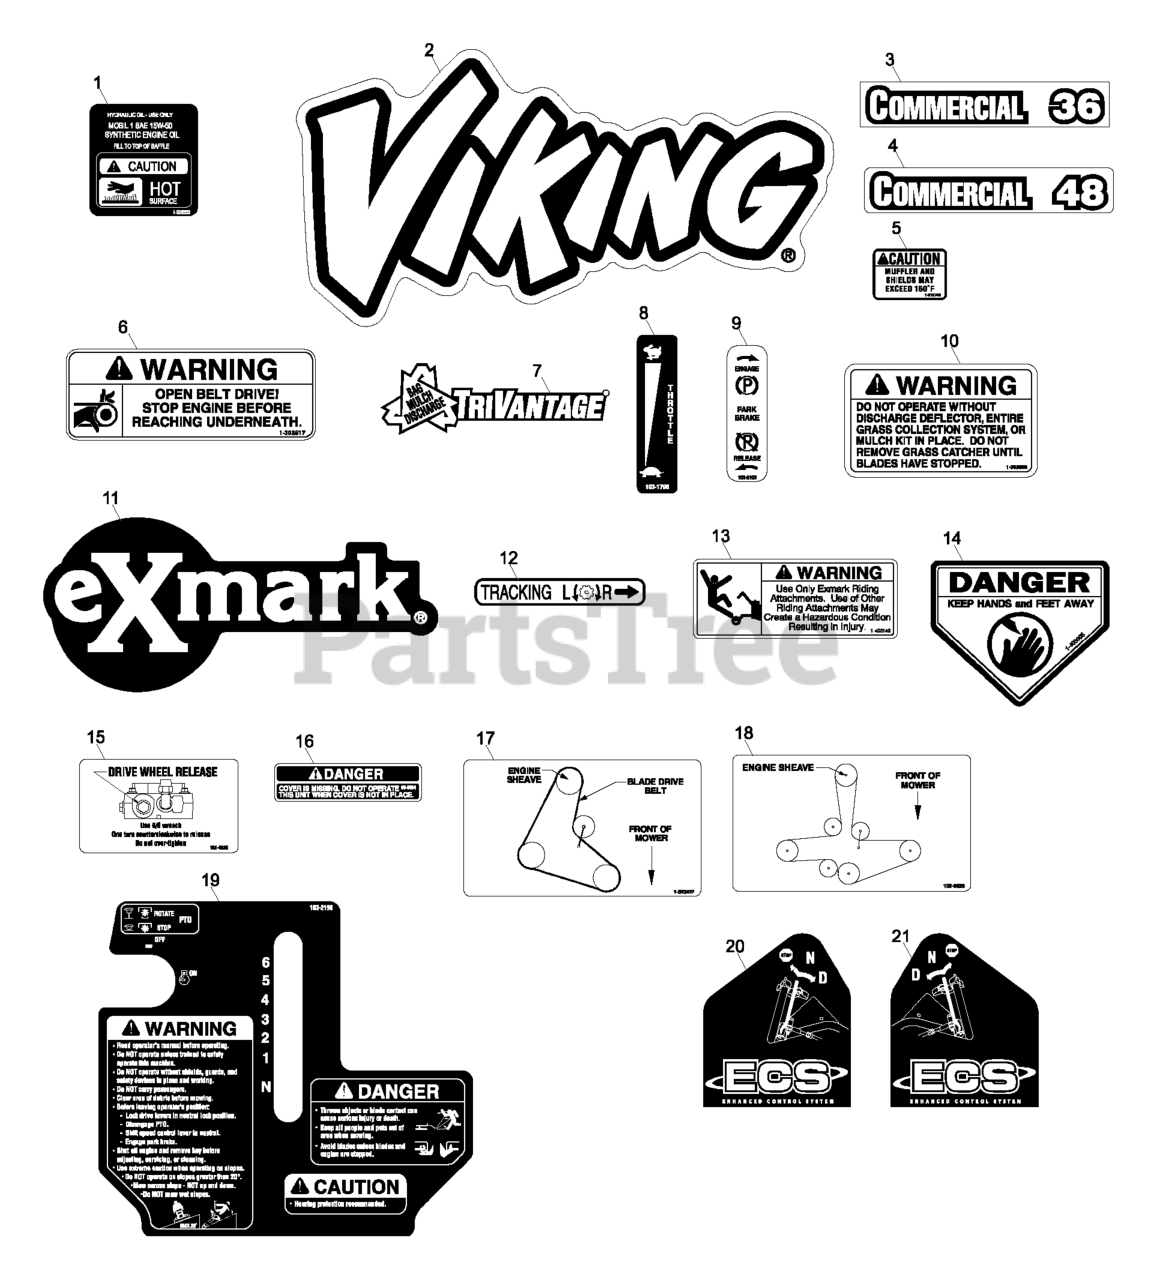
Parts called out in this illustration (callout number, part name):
2	DECAL,VH MODEL
3	DECAL,COMMERCIAL 36
4	DECAL,COMMERCIAL 48
6	DECAL,BELT DRIVE
8	DECAL,THROTTLE ONLY
9	DECAL-BRAKE, PARK
10	DECAL-WARNING, DISCHARGE
11	DECAL,EXMARK LOGO
12	DECAL,TRACKING ADJUST
13	DECAL,SULKY WARNING
14	DECAL-DANGER
15	DECAL,DRIVE RELEASE
16	DECAL-COVER, MISSING
17	DECAL,BELT ROUTING 32/36
18	DECAL,BELT ROUTING
19	DECAL,CONSOLE VH ECS
20	DECAL,LH ECS INSTRUCTION
21	DECAL,RH ECS INSTRUCTION
